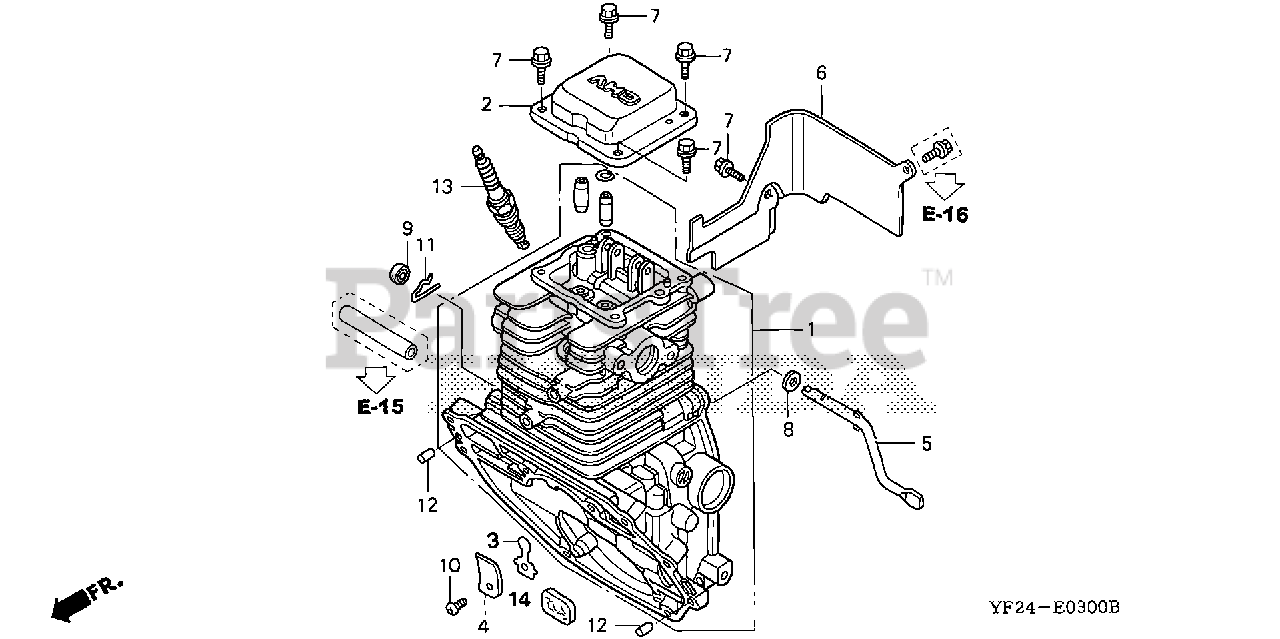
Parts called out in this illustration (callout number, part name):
1	CYLINDER
2	COVER, HEAD
3	VALVE, OIL OUTLET
4	PLATE, STOPPER
5	SHAFT, GOVERNOR ARM
7	BOLT, FLANGE (5X12)
8	WASHER (5.2X9)
9	OIL SEAL (5X11X5)
10	SCREW, PAN (3X5)
11	PIN, LOCK (6MM)
12	ROLLER (6X14.8)
12	ROLLER (6X15)
13	SPARK PLUG (U14FSR-UB)
13	SPARK PLUG (CR4HSB) (NGK)
13	SPARK PLUG (CR5HSB) (NGK)
14	FILTER, BREATHER
